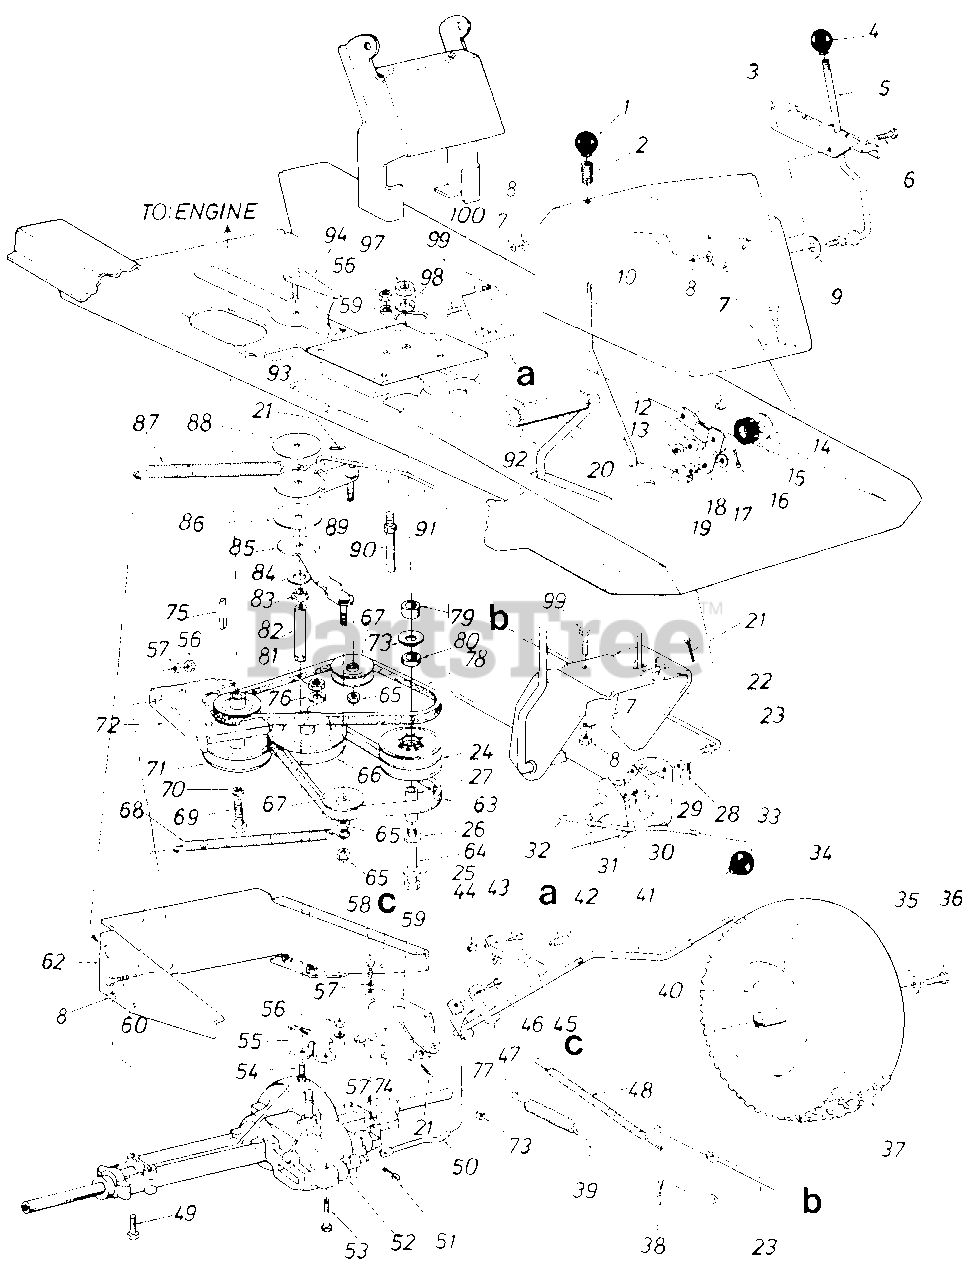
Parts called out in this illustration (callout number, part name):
1	Ball Knob 1/4-20 Thd. 1.25
2	Compression Spring
5	Speed Control Lever
6	Truss Mach. Scr. 5/16-18 x .75" Lg.
7	L-Wash. 5/16" I.D.
8	Hex Nut 5/16-18 Thd.
9	Bell-Wash. .345" I.D. x .88"
10	Brake Locking Rod
12	Bell-Wash. .345" I.D. x .08"
13	Hex Cent. L-Nut 5/16-18 Thd.
14	Fl-Wash. .50" I.D. x 1.5" O.D.
15	Rubber Washer
16	Intern. Cotter Pin 1/2" Dia.
17	Fl-Wash. .34" I.D. x .68" O.D.
18	Speed Control Lever Brkt. Ass'y.
19	Ferrule-Engagement
20	Clutch/Brake Pedal Ass'y.
21	Cotter Pin 3/32" Dia. x .75"*
22	Clutch/Brake Pedal Ass'y.
23	Brake Rod
24	Variable SPeed Pulley Ass'y.
25	Washer .40" I.D. x 1.25" O.D.
26	Thrust Brg. 1.25" O.D. x .56" I .D.
27	Spacer Sleeve 2.71"
28	Cotter Pin 1/8" Dia. x 1.25"
29	Fl-Wash. .34" I.D. x .60" O.D.
30	Intern. Cot-Pin 5/16" Dia.
31	Fl-Wash. .34" I.D. x .60" O.D.
32	Speed Control Rod
33	Ball Knob
35	Bell-Wash. .345" I.D. x .88"
36	Hex L-Bolt 5/16-24 x .75" Lg.
38	Cotter Pin 1/8" Dia. x 1.25"
39	Extension Spring 17.0" Lg.
40	Air Valve
43	C Sink AB S-Tap Scr. #8 x .50" Lg.
44	Push-in Nut #10
45	Spring Switch
46	Hex Bolt 1/4-20 x .50" Lg.
47	Shift Lever Adjusting Link
48	Ext. Spring 81/4" Lg.
49	3/16-18 x 2.50 Hex Bolt
50	Shift Rod
51	Intern. Cotter Pin
52	Transaxle
53	Hex Bolt 1/4-20 x 1.75" Lg.
54	Hex Bolt 3/8-24 x .75" Lg.
55	Torque Rod Bracket
56	Hex Nut 1/4-20 Thd.
57	L-Wash. 1/4" I.D.
58	Self-Tap Mach. Scr. Type "C" 1/4-20 x 1.37" Lg.
59	Shift Lever Support Brkt.
60	Hex Bolt 1/4-20 x 1.00" Lg.
62	Transaxle Support Ass'y.
63	V-Belt
64	Hex Bolt 3/8-16 x 4.5" Lg.
65	Hex Ins. L-Nut 3/8-24 Thd.
66	5/8 V-Pulley .500" I.D. x 6"
67	V-Belt Idler .38" I.D. x 3.06"
68	Ext. Spring .50" O.D. x 6.37"
69	Hex Bolt 7/16-20 x 1.00" Lg.
70	L-Wash. 7/16" I.D.
71	Engine Pulley
72	Upper Eng. Belt Guard
73	Bell-Wash. 1.12 O.D. x .40
74	Spacer .256" I.D. x .50" O.D.
75	Sq.-Key 1/4" x 2.00" Lg.
76	L-Wash. 1/2" I.D.
77	Fl-Wash. .469" I.D. x .88" O.D.
78	V-Belt
79	Spacer 1.00" x .380" O.D.
80	Thrust Bearing 1.25 O.D. x .56 I.D. x .06
81	Hex Nut 1/2-20 Thd.
82	Torque Rod
83	Flange Bearing .378
84	Fl-Wash. .640" I.D. x 1.24"
85	Idler Bracket Ass'y.
86	Thrust Wash. .635" I.D.
87	Extension Spring 7.58" Lg.
88	Thrust Wash. .385" I.D.
89	Idler Bracket Ass'y. For Clutch
90	Belt Guard Pin 1/4" Dia.
91	Clutch Rod
92	Foot Pad
93	Mtg. Brkt. Variable Pulley
98	L-Wash. 3/8 Heavy Duty
99	Hex Bolt 5/16-18 x .75" Lg.
100	Shift Lever Spring Brkt.
16389-0637	BRACKET-SP INDEX (POWDER BLACK) - POWDER BLACK (0637)
16389-0638	BRACKET-SP INDEX - MTD/TROY-BILT RED (0638)
